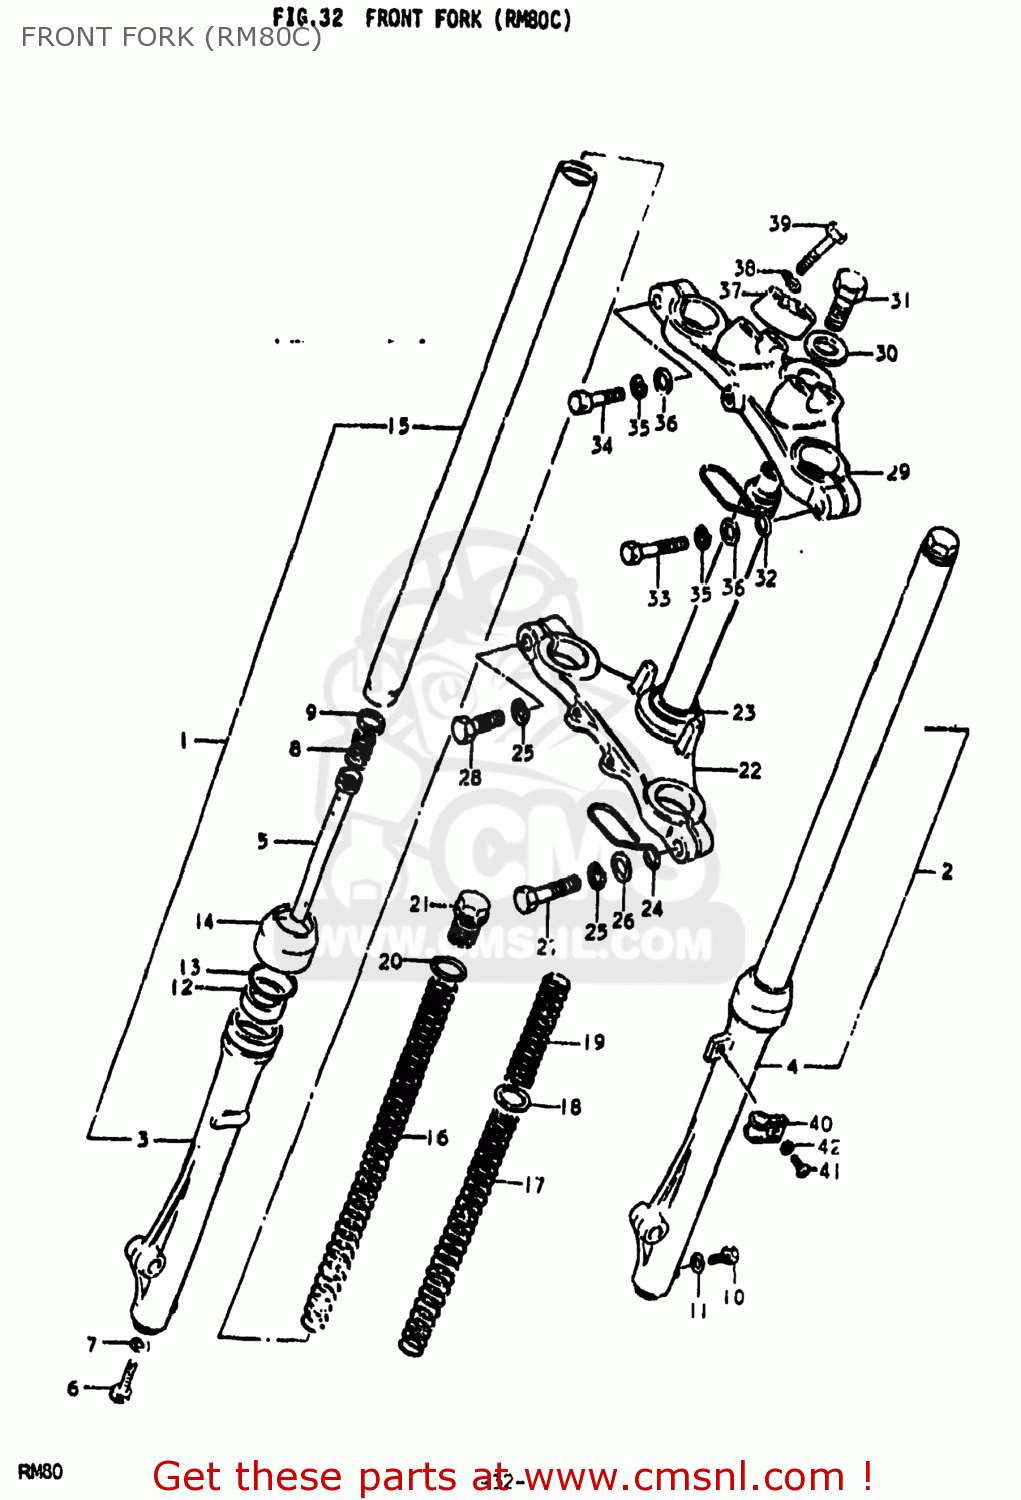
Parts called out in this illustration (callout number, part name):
0	DAMPER SET
1	DAMPER ASSEMBLY,RIGHT
2	DAMPER ASSEMBLY,LEFT
3	TUBE,OUTER,RIGHT
4	TUBE,OUTER,LEFT
5	CYLINDER,FRONT FORK
6	BOLT
7	GASKET (NAS)
8	SPRING,REBOUND
9	RING,PISTON
10	BOLT(6X8)
11	GASKET,DRAIN,PLUG (NAS)
12	OIL SEAL,FRONT FORK
13	RING,OIL SEAL STOPPER
14	BOOT
15	TUBE,FORK,INNER
16	SPRING
17	SPRING
18	JOINT,SPRING
19	SPRING,FRONT FORK
20	O-RING,FORK INNER TUBE
21	CAP,FORK
22	STEM,STEERING
23	RACE,STEERING OUTER LWR
24	CLAMP,METER CABLE
25	LOCK WASHER
26	WASHER
27	BOLT
28	BOLT,M10X1.25X
29	HEAD,STEERING STEM
30	WASHER(10.5X30X2.3)
31	BOLT
32	CLAMP,METER CABLE
33	BOLT 8X40
34	BOLT
35	LOCK WASHER
36	WASHER
37	HOLDER,HANDLEBAR
38	LOCK WASHER
39	BOLT
40	CLIP,FR BRAKE CABLE
41	SCREW
42	LOCK WASHER
